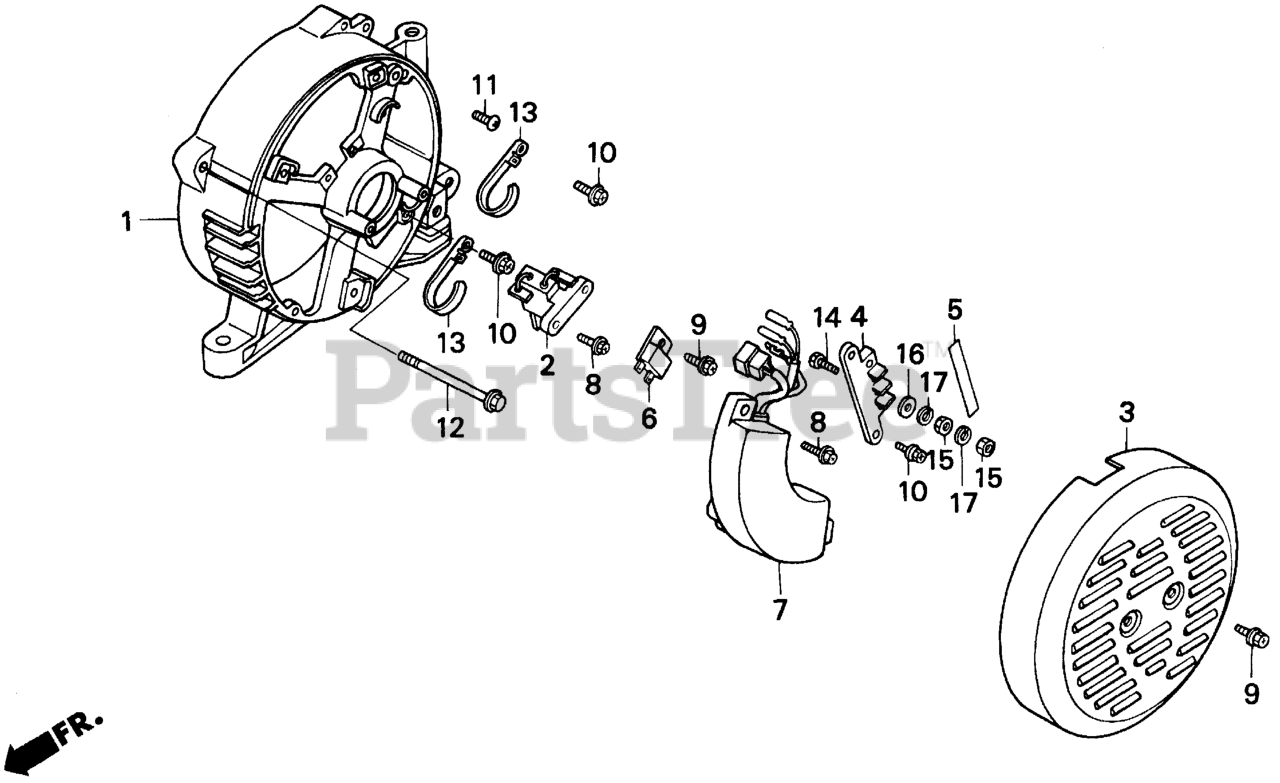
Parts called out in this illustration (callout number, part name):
1	HOUSING, RR. *R8* (BRIGHT RED) (NOT AVAILABLE)
1	HOUSING, RR. *R8* (BRIGHT RED)
1	HOUSING, RR.
2	BRUSH ASSY.
3	COVER, GENERATOR END *R8* (BRIGHT RED)
4	TERMINAL, VOLT CHANGE
5	MARK, VOLT
6	DIODE, D.C.
7	REGULATOR ASSY., AUTOMATIC VOLTAGE
8	SCREW, TAPPING (5X18)
9	SCREW, TAPPING (5X12) (GROUND CABLE)
10	SCREW, TAPPING (5X14)
11	SCREW, PAN (5X12) (GROUND CABLE)
12	BOLT, FLANGE (6X160)
13	TIE, CABLE
14	BOLT, HEX. (5X20)
15	NUT, HEX. (5MM)
16	WASHER, PLAIN (5MM)
17	WASHER, SPRING (5MM)
